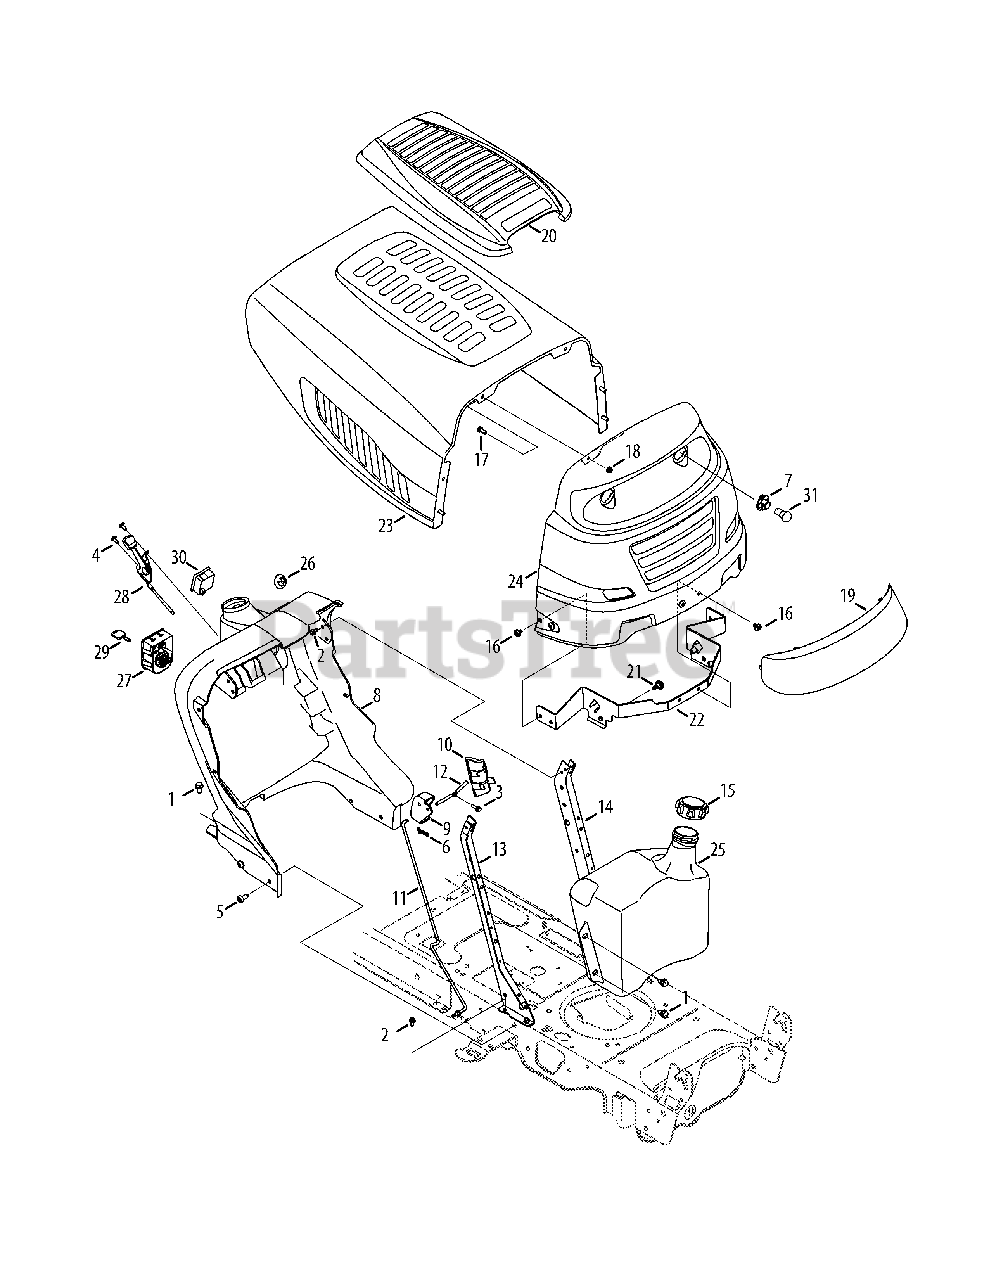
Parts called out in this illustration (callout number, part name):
1	Taptite Screw ,5/16-18 x .750
2	Taptite Screw ,1/4-20 x 0.500
3	Hi-Lo Screw, 1/4-15 x 0.750
4	Screw, 1/4-14 x 0.625
5	Taptite Screw ,5/16-18 x 0.750
6	Bow Tie Cotter Pin
7	Lamp Socket
8	Dash Panel, No Sight Window
9	Dash Lever
10	Cruise Cover
11	Control Rod
12	Lever
13	RH Support Plate
14	LH Support Plate
15	Fuel Cap, EPA
16	Taptite Screw ,5/16-18 x 0.375
17	Hex Screw, 1/4-20 x .620
18	Flangelock Nut, 1/4-20
19	Grill Lens
20	Hood Scoop
21	Shoulder Screw, .43X.29 x 5/16-18
22	Hood Pivot Bracket
25	Fuel Tank, EPA
26	Choke Plug
27	Key Switch Module
28	Throttle/Choke Control
29	Key, Assembly
30	Hour Meter
